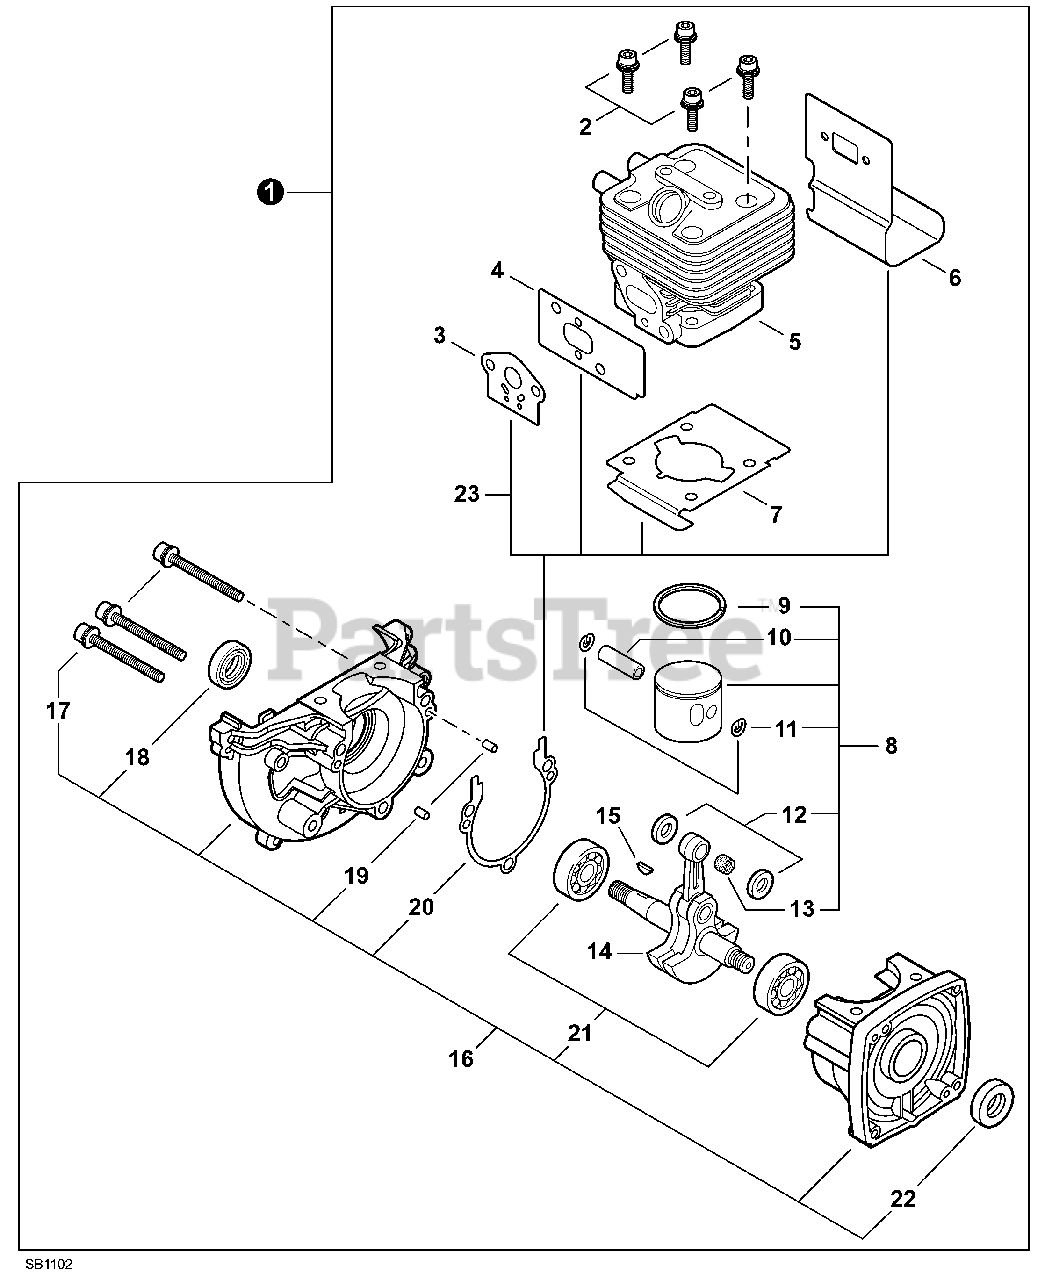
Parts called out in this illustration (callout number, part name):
1	SHORT BLOCK SB1102
2	BOLT 5×25
3	GASKET, INTAKE
4	HEAT SHIELD, INTAKE
5	CYLINDER
6	HEAT SHIELD, EXHAUST
7	GASKET, CYLINDER
8	PISTON KIT
9	RING, PISTON
10	PIN, PISTON
11	RING, SNAP
12	WASHER, THRUST
13	BEARING, NEEDLE 9
14	CRANKSHAFT ASSY
15	KEY, WOODRUFF
16	CRANKCASE KIT
17	BOLT 5×28
18	SEAL, OIL 12
19	PIN, LOCATING 4×8
20	GASKET, CRANKCASE
21	BEARING, BALL - 6201 C3
22	SEAL, OIL 12
23	GASKET KIT
